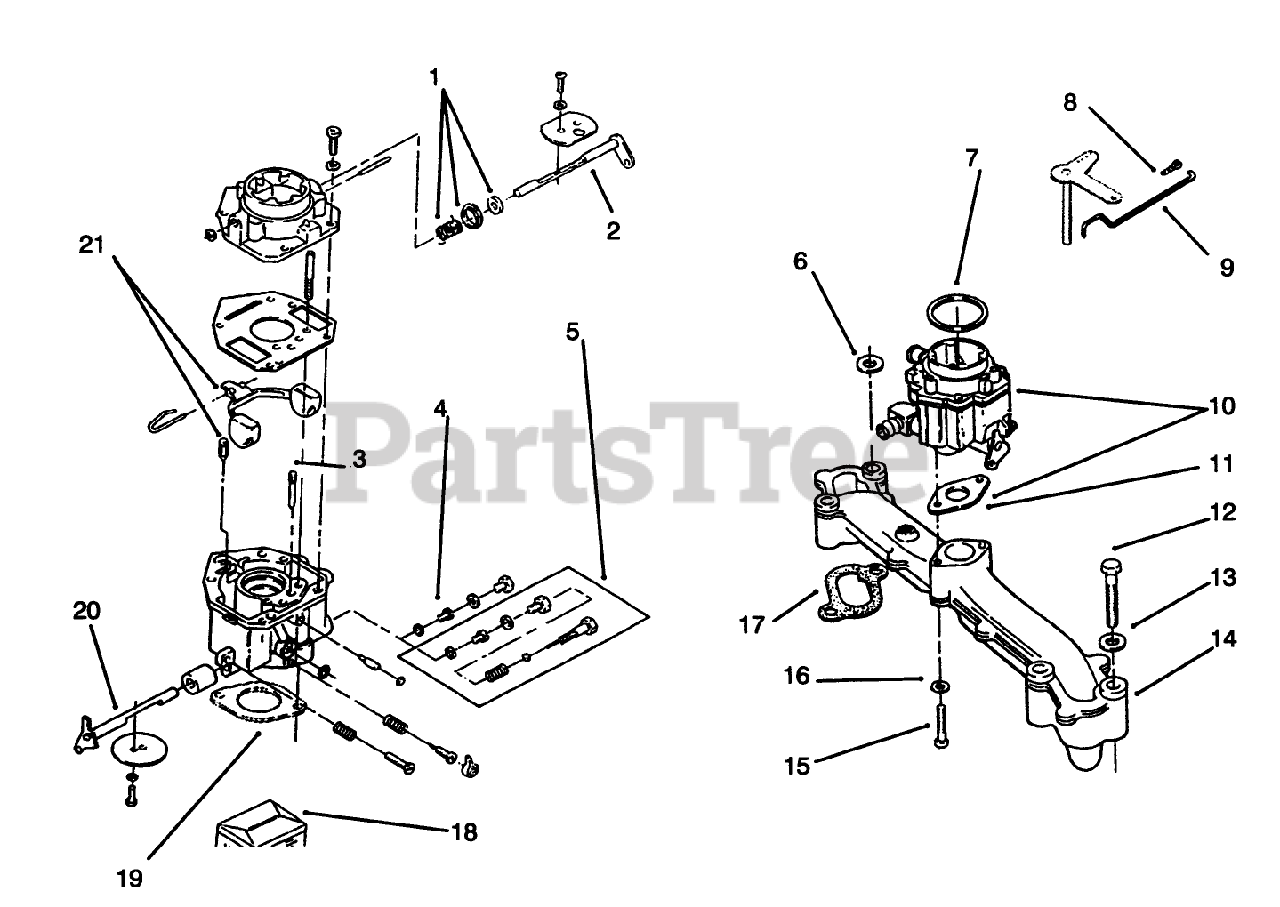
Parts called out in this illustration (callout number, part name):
1	CHOKE KIT LEVER
2	CHOKE KIT SHAFT
3	IDLE JET
4	POWER JET
5	Kit-Variable Jet
6	WASHER-PLAIN
9	CONTROL ROD
10	Carburetor-Complete
11	Gasket
12	SCREW-HH
13	WASHER-PLAIN
14	INTAKE MANIFOLD KIT
15	SCREW-HH
16	WASHER-FLAT
17	GASKET
18	Repair Kit
19	Gasket
20	Shaft-Throttle
21	FLOAT
